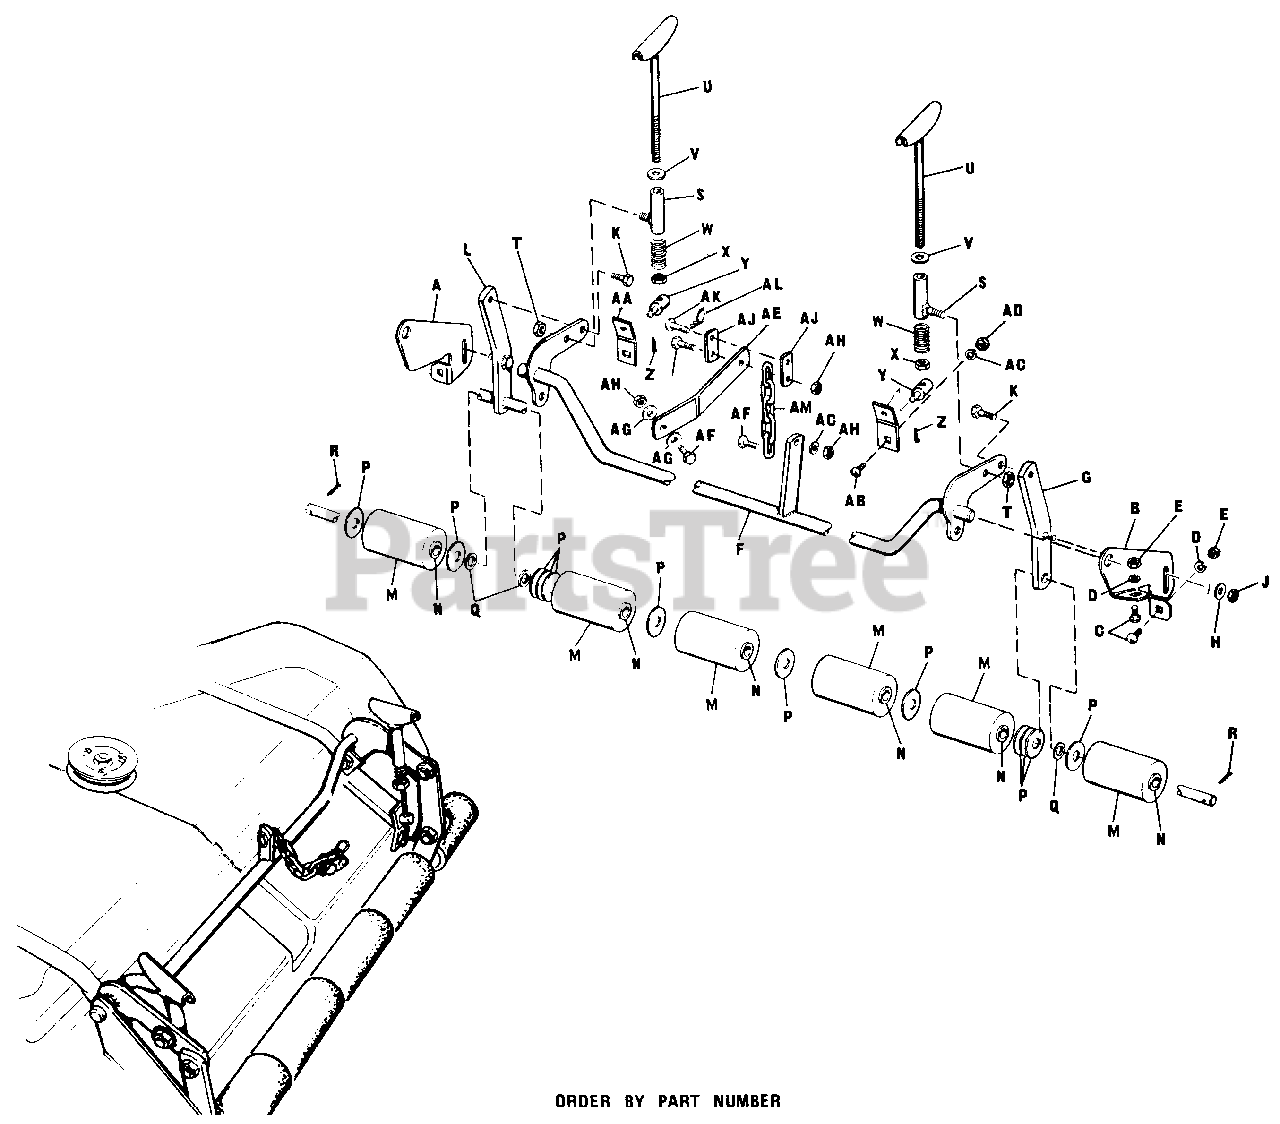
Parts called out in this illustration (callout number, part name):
A	R.H. Roller Bracket
B	L.H. Roller Bracket
C	Carriage Bolt, 3/8"-16 x 3/4"
D	Lock Washer 3/8"
E	Full Hex. Nut, 3/8"-16
F	Rocker Assembly Arm
G	Roller Bar Assembly L.H.
H	Plain Washer, 3/8"
J	Full Hex. Nut, 3/8"-16
K	Hex. Cap Screw, 3/8"-16 x 1"
L	Roller Shaft Assembly
M	Roller W/Bushing
R	Cotter Pin, 3/16"-1"
S	Socket Crank Assembly
T	Full Hex. Nut, 3/16"-16
U	Adjusting Screw Assembly
V	Plain Washer 3/8"
W	Adjusting Screw Spring
X	Hex. Jam Nut, 3/8"-16
Z	Cotter Pin, 3/32" x 3/4"
AA	Lift Link
AB	Carriage Bolt, 3/8"-16 x 3/4"
AC	Lock Washer, 3/8"
AD	Full Hex. Nut, 3/8"-16
AE	Mower Lift Lever
AF	Hex. Cap Screw, 3/8"-16 x 1"
AG	Plain Washer, 3/8"
AH	Full Hex. Nut, 3/8"-16
AJ	Mower Lift Link
AL	Spring Clip
